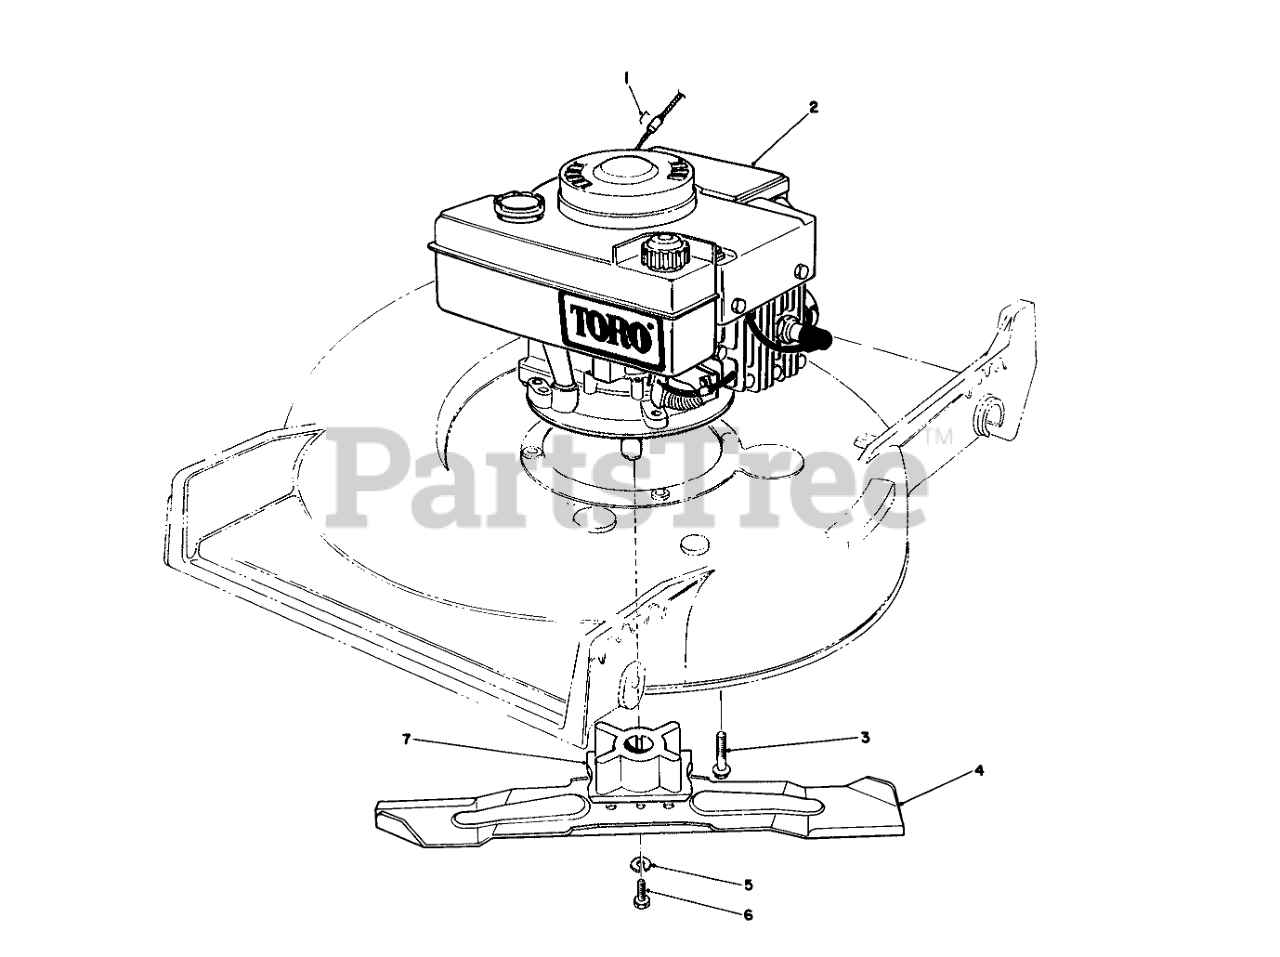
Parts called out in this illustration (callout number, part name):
1	Staple
3	3/8-16 X 2 CAPSCREW
4	BLADE-21in
5	WASHER-LOCK
6	SCREW-BLADE
7	BLADE RETAINER
